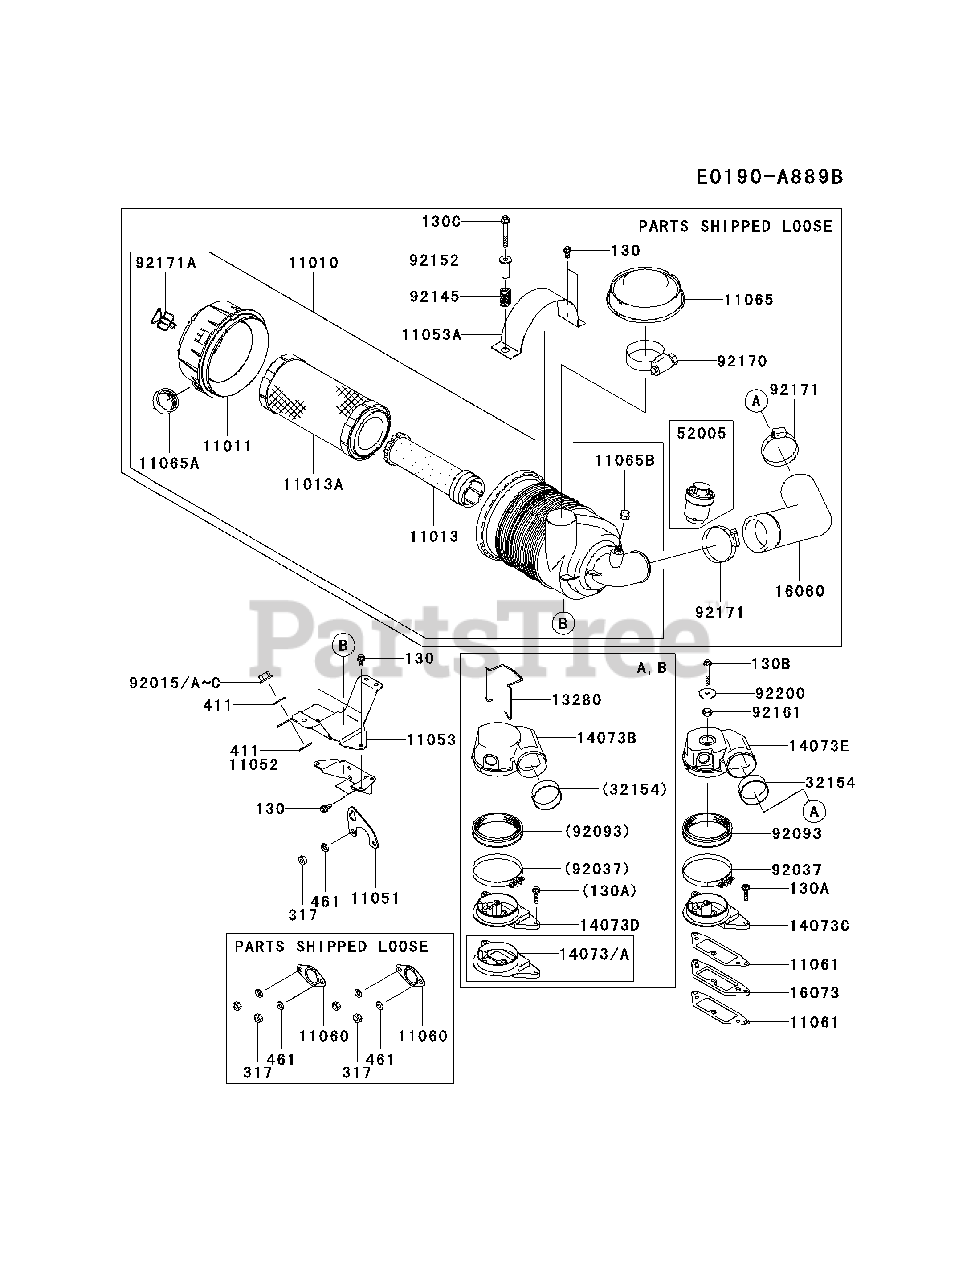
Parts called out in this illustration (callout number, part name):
130A	BOLT-FLANGED,6X25
130B	BOLT-FLANGED,6X45
130C	BOLT-FLANGED,8X55
317	NUT-HEX-SMALL,8MM
411	WASHER-PLAIN,6MM
461	WASHER-SPRING,8MM
